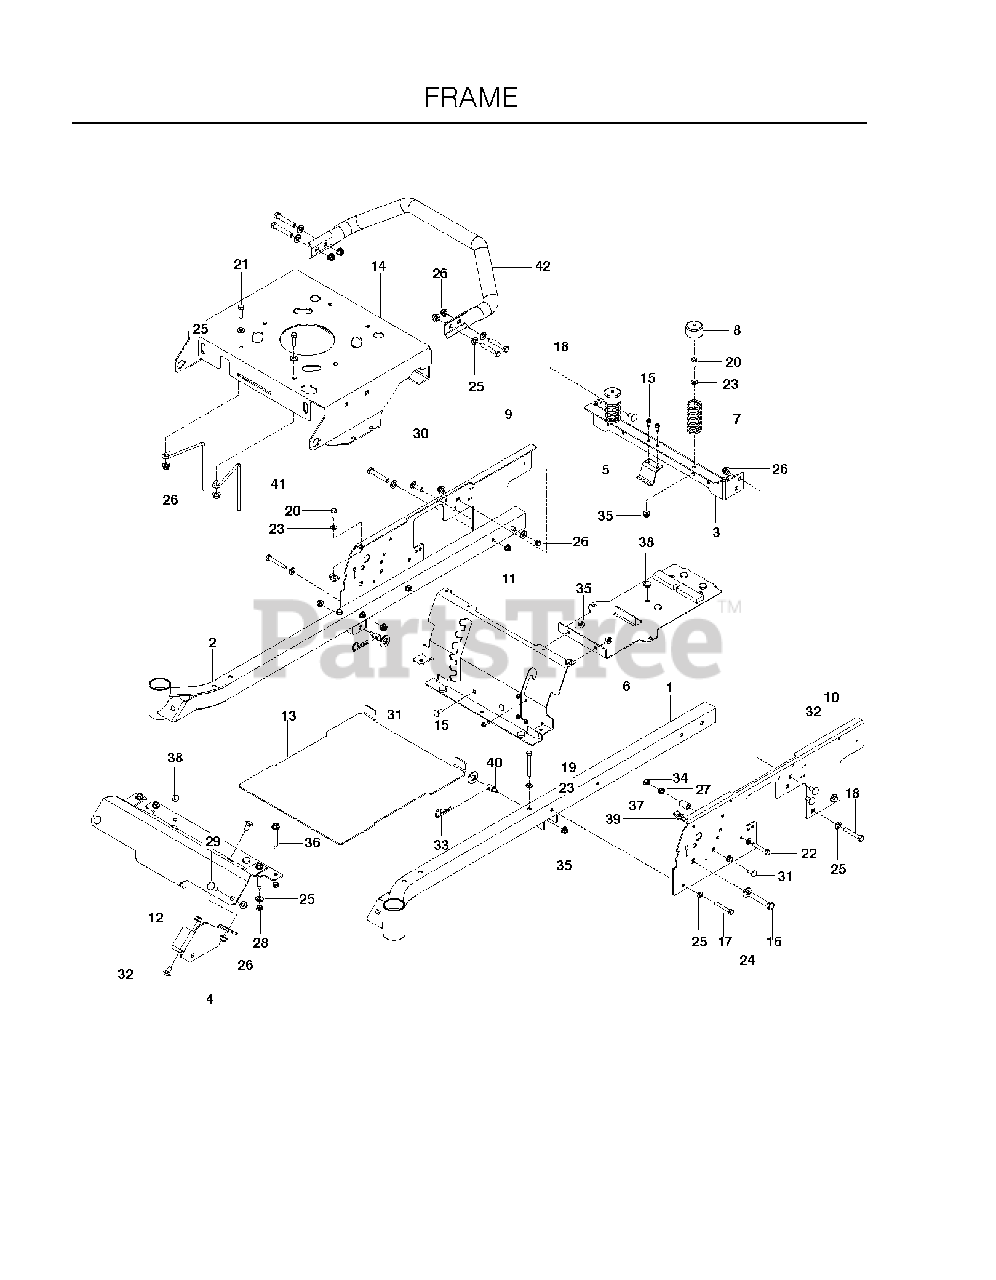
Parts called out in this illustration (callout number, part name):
1	FRAME TUBE, LH, ORG
2	FRAME TUBE, RH, ORG
3	SUPPORT, REAR SEAT, ORG
4	BRACKET, FRONT DECK, BLK
5	HOLDING DEVICE, FUEL TANK, BLK
6	SUPPORT, TANK/BATT, BLK
7	SEAT SPRING
8	SPRING CAP
9	PLATE, LH SIDE, ORG
10	PLATE, RH SIDE, ORG
11	PANEL, SEAT SUPP. ORG
12	FOOT, REST 30/38, ORG
13	FOOT PLATE NARROW ORG
14	PLATE ENGINE ORG
15	SCREW 1/4 X 5/8
16	HCS 1/2C X 2 3/4
17	CAPSCREW
18	HCS 3/8C X 2 1/4
19	HCS 5/16C X 2-3/4
20	HCS 5/16C X 3/4
21	HCS 3/8C X 1 1/4 GR5
22	HCS 5/16-18X2
23	FLAT WASHER 5/16 SAE
24	WASHER 1/2" FLAT
25	WASHER 3/8 SAE FLAT
26	NUT 3/8-16 HEX FLG NYLOC ZD
27	NUT 5/16C WHIZ
28	NUT HEX 3/8-16 NYLON, THIN
29	RHSNB 3/8C X 1
30	RHSNB 3/8-16 X 1-1/4
31	BOLT 5/16C X 3/4" CARRIAGE
32	RHSNB 3/8-16 X 3/4 GR5 ZD
33	HAIRPIN #4
34	NUT 5/16 NYLOC
35	5/16-18 NYLOC FLANGE NUT
36	ENGINE BOLT, SPECIAL
37	BUSHING
38	GROMMET, BUMPER
39	U-CLIP 5/16-18 NUT RETAINER
40	STUD.FASTNER.W/ANTI-ROTATE
41	BELT GUIDE
42	IMPACT BAR, ORG
